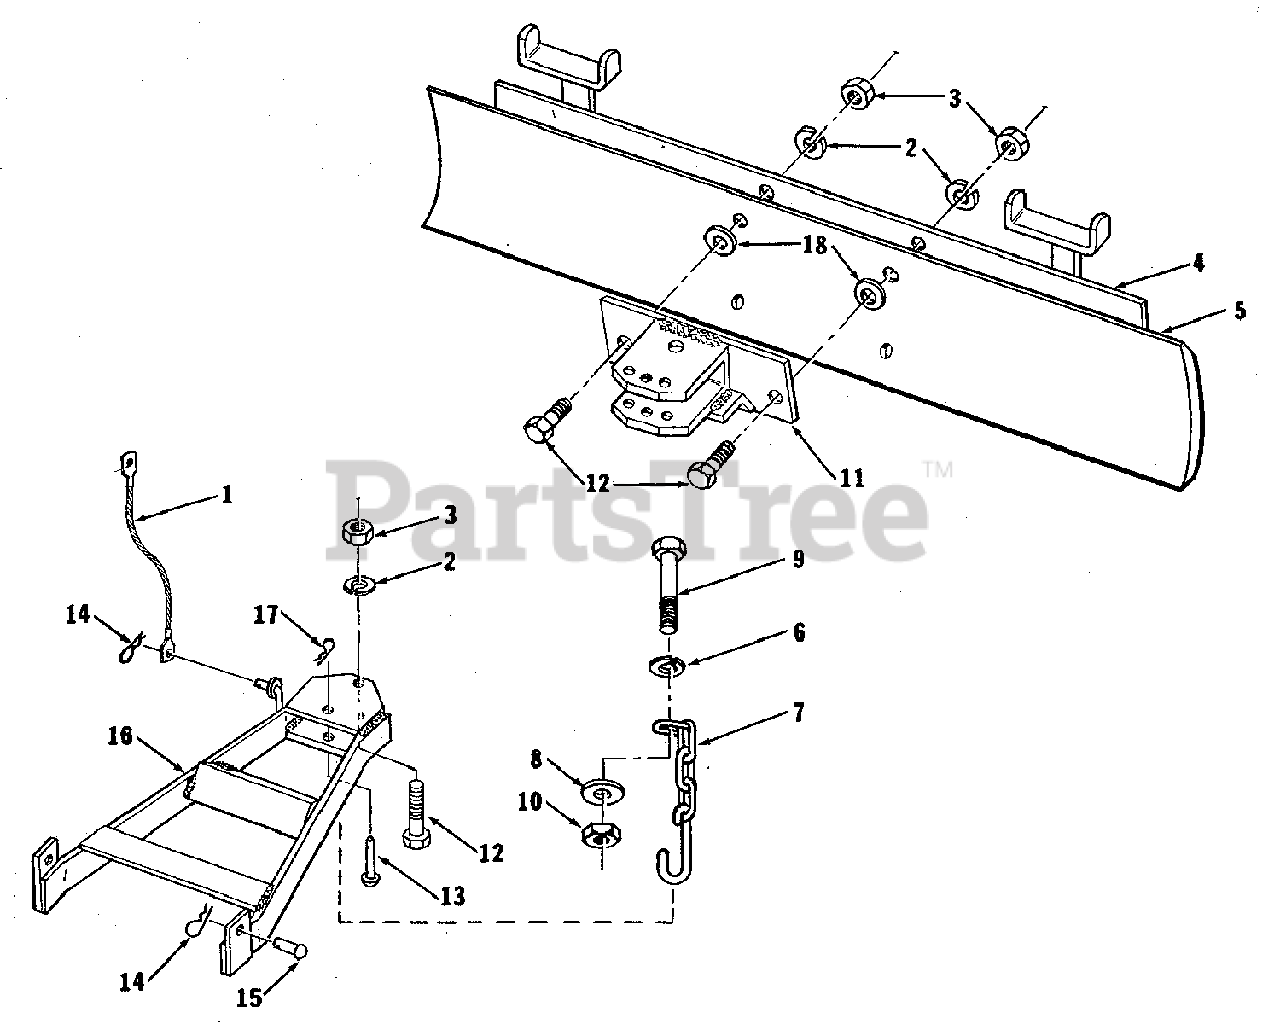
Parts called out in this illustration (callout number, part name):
1	CABLE ASSEMBLY, Lift
2	WASHER, Lock, 5/8
3	NUT, Hex, 5/8-11
4	BRACKET ASSEMBLY
5	BLADE, Grader, 42"
6	WASHER, Lock, 3/8
7	HOOK, Transport Lift
8	WASHER, Flat, 3/8
9	SCREW, Hex Cap, 3/8-16 x 1-1/4
10	NUT, Hex, 3/8-16
11	HITCH ASSEMBLY
12	SCREW, Hex Cap, 5/8-11 x 3
16	DRAW BAR ASSEMBLY
